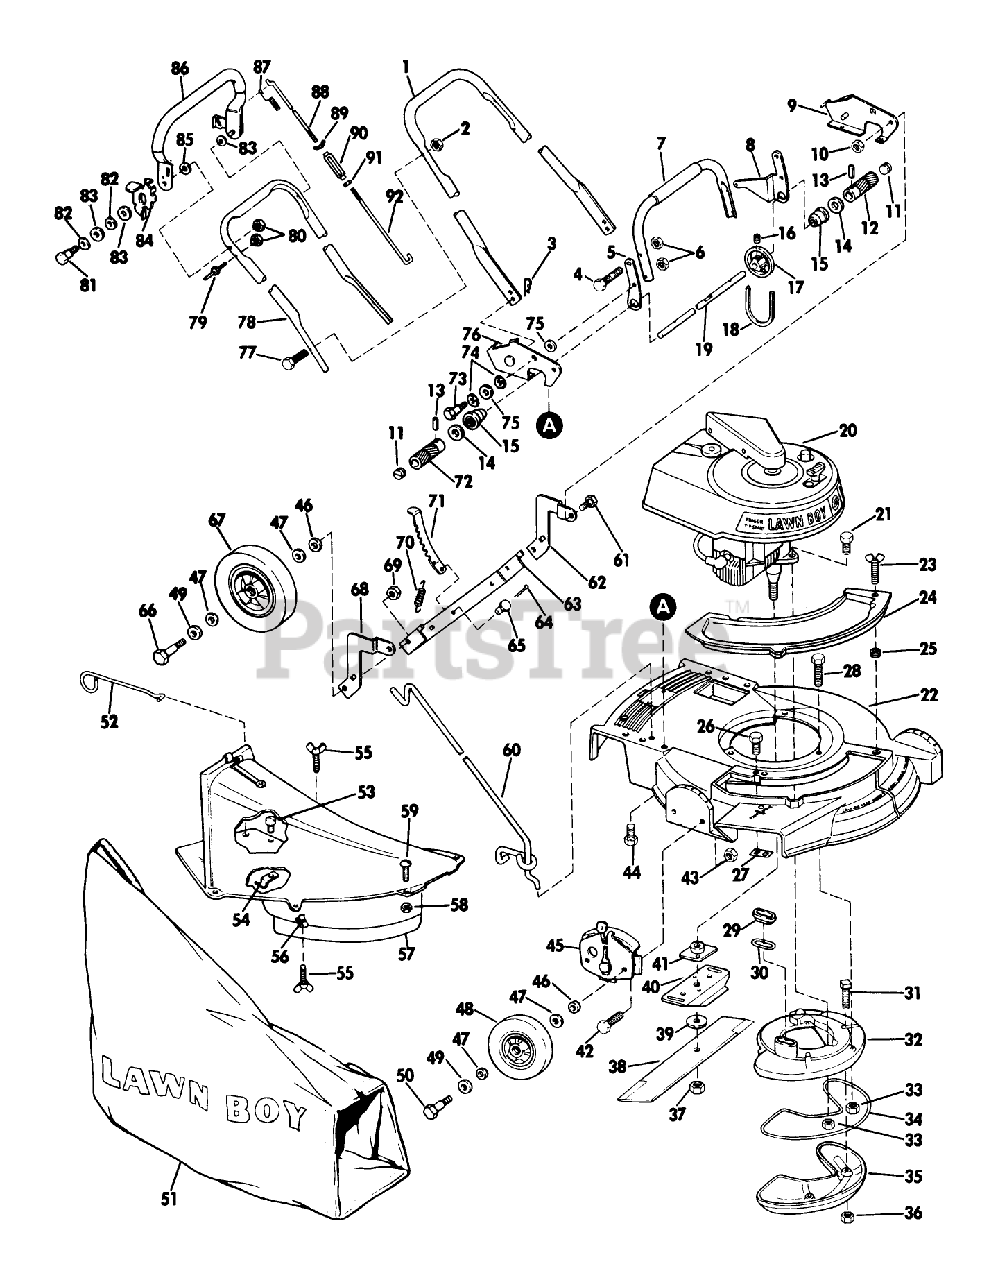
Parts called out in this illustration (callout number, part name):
3	HAIR PIN
11	GREASE PLUG
12	LEFT ROLLER
30	GASKET S
36	LOCKNUT E
37	NUT-BLADE
41	PLATE AND COLLAR ASM
46	WASHER WROUGHT
50	BOLT WHEEL
51	89802 LB WHOLE GOODS
56	SPEED NUT ARDEN
57	Chute Skirt Assembly (Includes Hardware)
61	BOLT-SHOULDER
69	LOCKNUT
70	SPRING N.A.S
73	BOLT PIONEER
75	WASHER M
81	BOLT PIONEER
83	WASHER M
